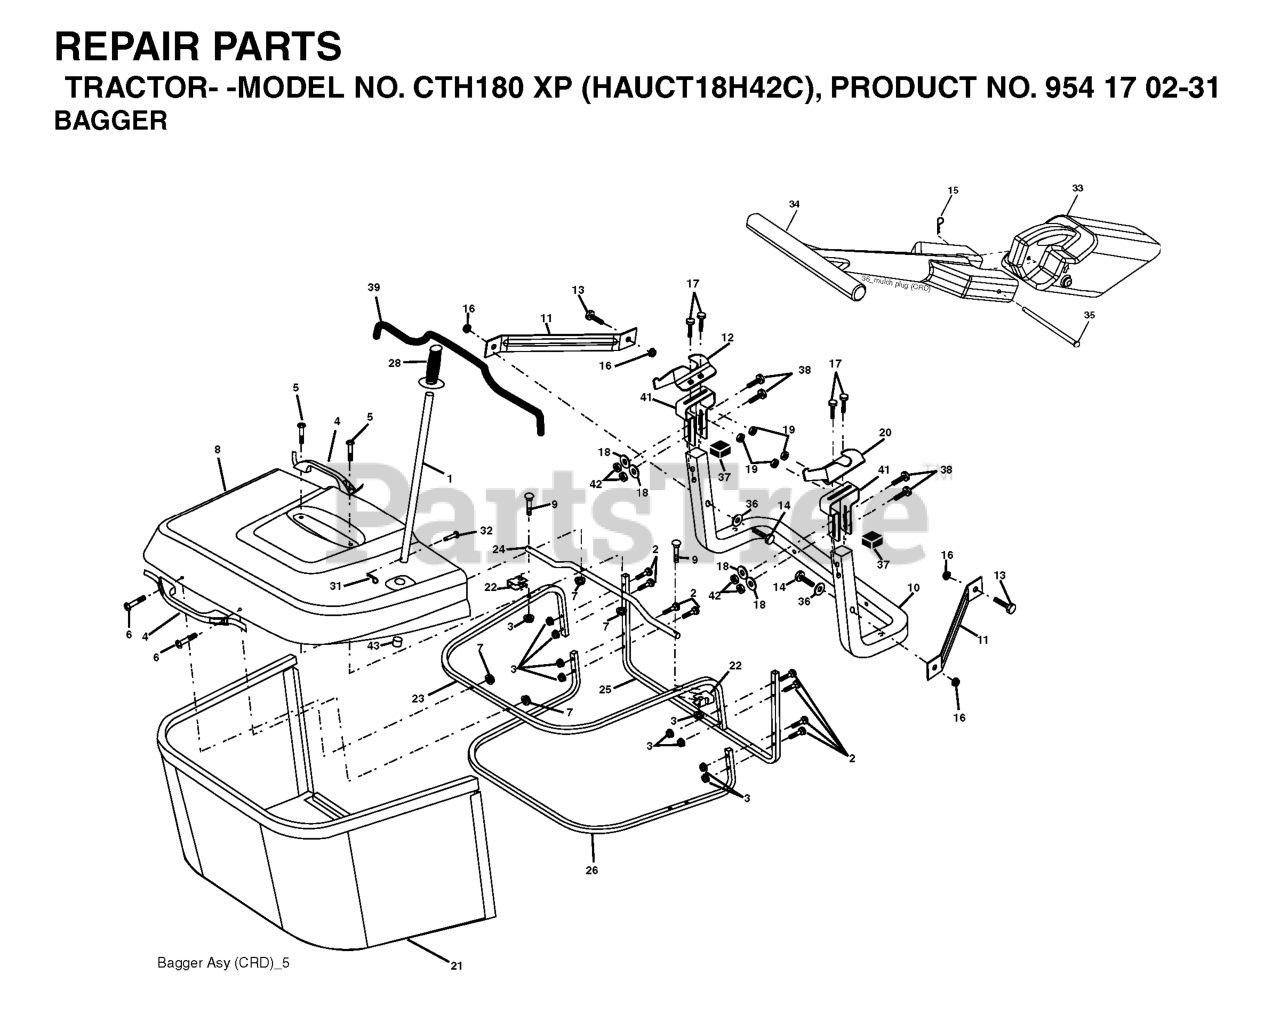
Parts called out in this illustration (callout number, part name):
1	TUBE HANDLE
2	Bolt Carriage 1/4-20 x 2.0 Gr.5
3	NUT T
4	HANDLE.BAGGER.W/LVRS.BLK.CRD
5	SCREW.PAN.HEAD
6	REPL BY 532 75 00-29
8	COVER.PNT.BGR.CRD.WSLOTS.MS668
9	Bolt Carriage 1/4-20 x 2.25d x Gr.5
10	TUBE
11	BRACKET.SUPPORT.UPPER.BAG.CRD
12	BRKT PIVOT
14	BOLT-HEX EAK
15	RETAINER-SPRNG RB
16	NUT LOCK FLG 3/8-16 UNC
17	RP BOLT 5/16-18 X3/4 ZN/YEL GR
18	WASHER M
19	NUT LOCK HEX FLANGE 5/16-18
20	BRKT.PIVOT.RH.CRD
21	GRASS BAG
22	BRKT.SIDE.BAG.CRD
23	TUBE.UPPER.BAG.CRD
24	TUBE.PIVOT.BAG.CRD.BLACK
26	TUBE.LOWER.BAG.CRD
28	GRIP.HANDLE.BLACK
31	RETAINER CLIP
32	RIVET,DRILLED
33	MULCH PLUG, CTH150
34	HANDLE.MULCHER.92.CRD (2 2)
36	WASHER
37	Plug Support Bagger CRD
38	BOLT.5/16-18X2.5
39	SEAL.TRIM.37'
41	BRKT.VERT.ADJ.BAGGER.CRD
42	NUT LOCK HEX FLANGE 5/16-18
43	PLUG, TUBING END
